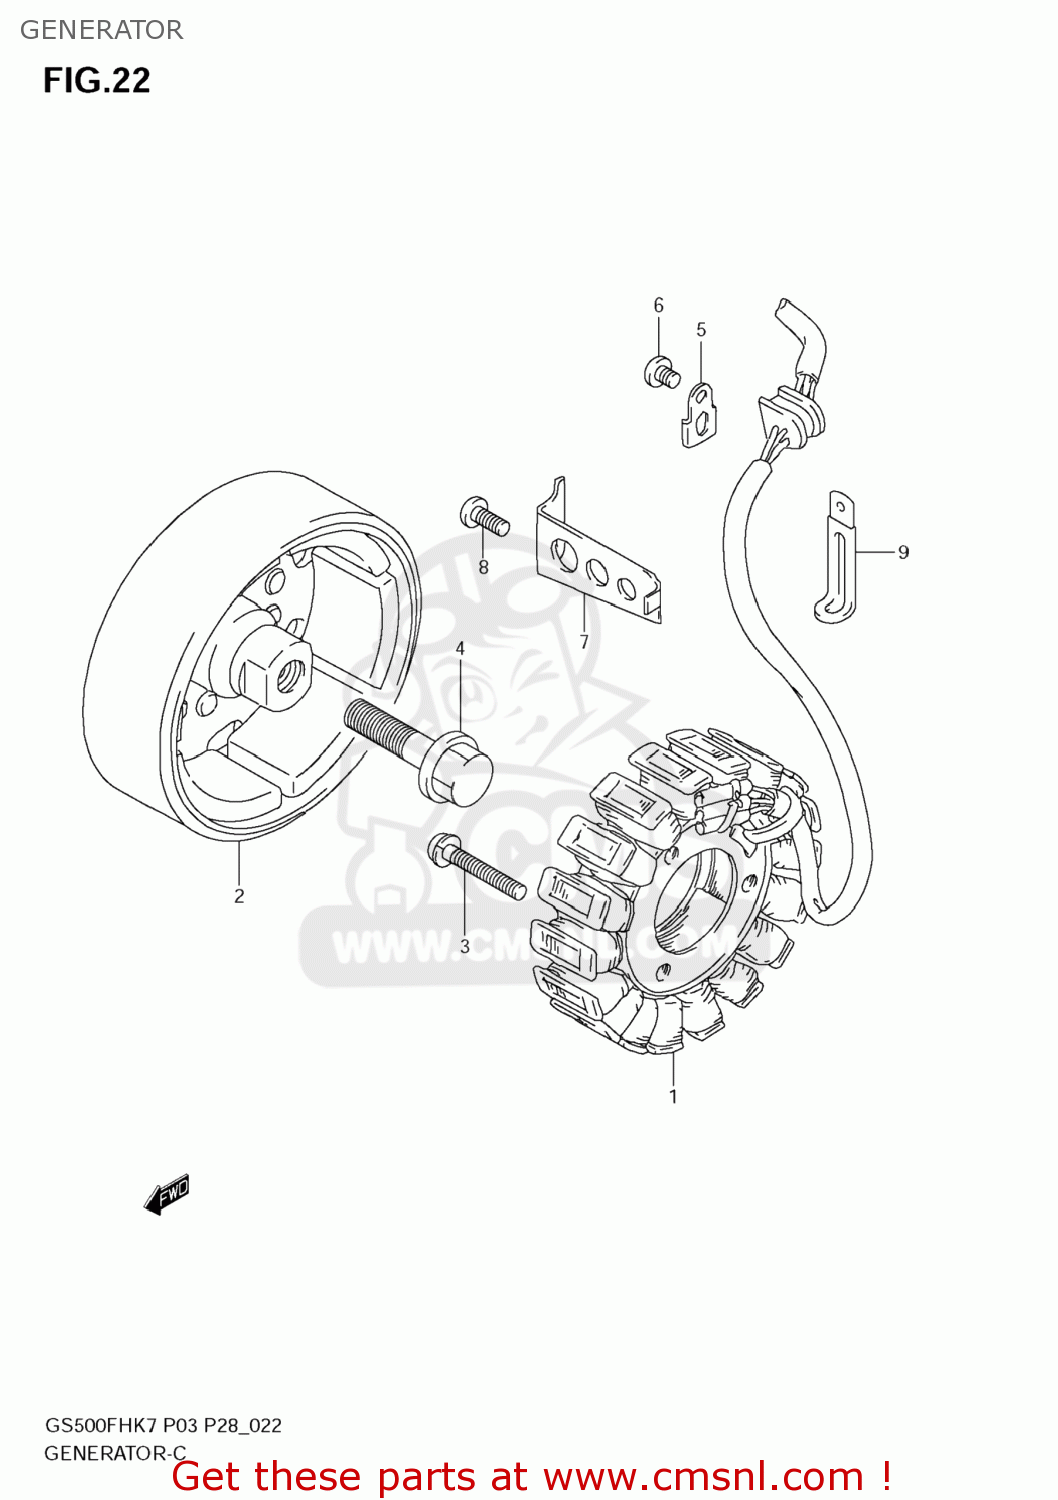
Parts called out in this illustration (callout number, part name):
1	STARTER ASSY
2	ROTOR
3	SCREW
4	BOLT(12X40)
5	CLAMP,GENERATOR LEAD WIRE
6	SCREW
7	CLAMP,GENERATOR LEAD WIRE
8	SCREW, CENTER SHAFT
9	CLAMP(L:45)
